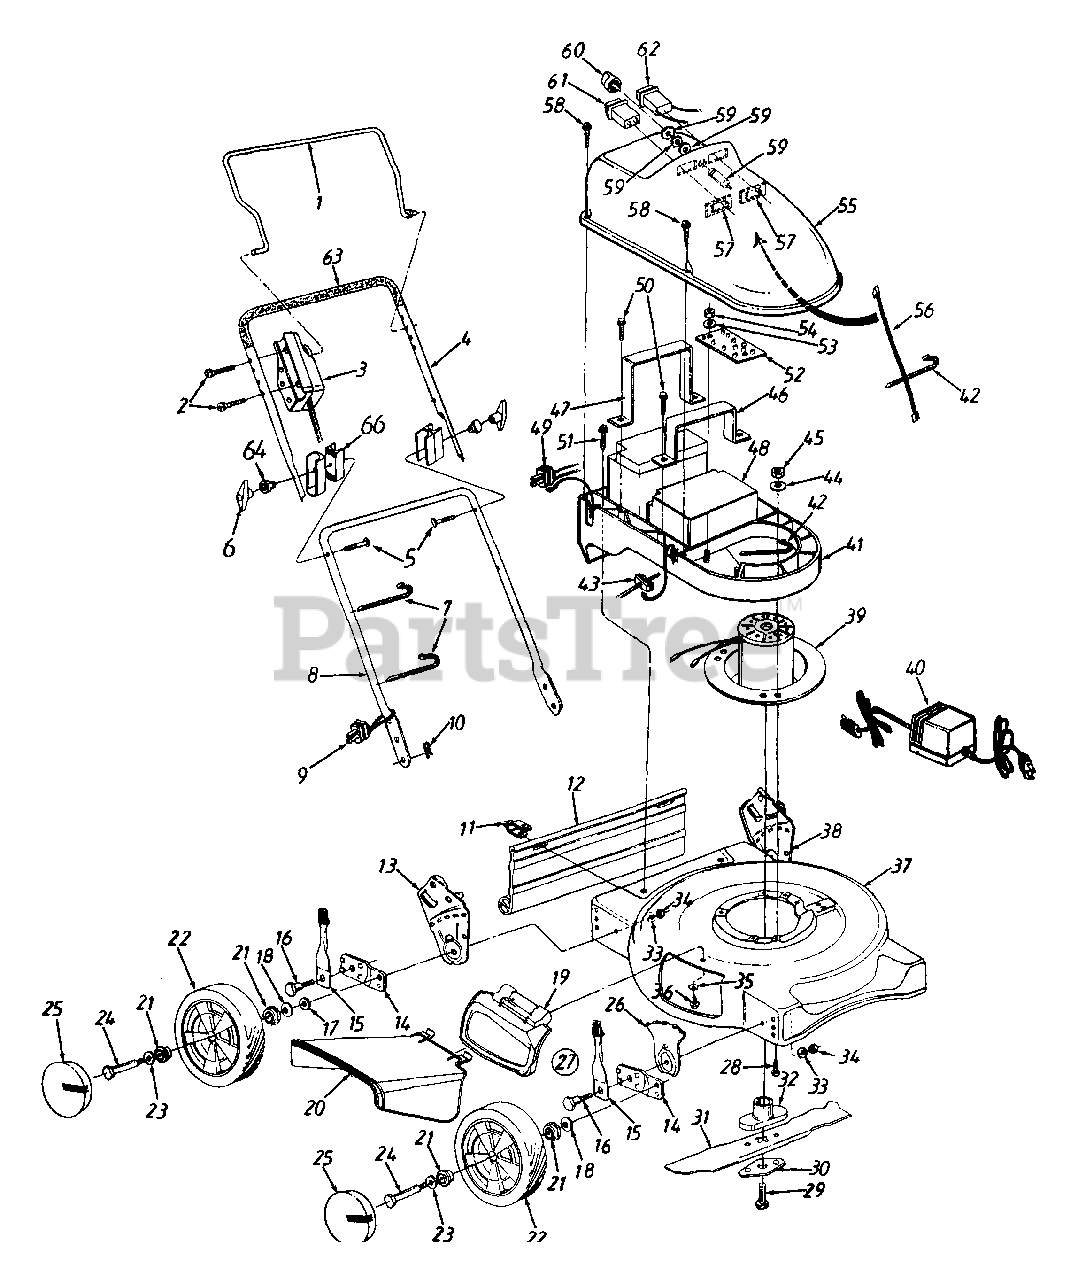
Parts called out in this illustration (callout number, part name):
1	Control Handle
2	C-Sunk Scr. 1/4-20 x 1.8" Lg.
3	Switch Ass'y.
6	Hand Knob
7	Cable Tie
8	Lower Handle
10	Hairpin Clip
11	Hinge Clip
12	Rear Flap
13	Handle Brkt. Ass'y. - R.H.
15	Spring Lever Ass'y. w/Knob
16	Shld. Bolt .5" Dia. x .43" Lg.
17	Fl-Wash. .385" I.D. x 1" O.D.
18	Bell-Wash. .38" I.D. x .88" O.D.
19	Mulching Plug Ass'y.
20	Chute Deflector
21	Ball Bearing
22	Wheel Ass'y.
23	Wave Wash. .51" I.D. x .75" O.D.
24	Shld. Bolt .498" Dia. x 1.45
25	Hub Cap
26	Height Adj. Plate
27	Height Adj. Ass'y. Comp. - R.F.
27	Height Adj. Ass'y. Comp. - L.F.
28	Hex Wash. Self-Tap Scr. 3/8-16 x 1" Lg.
29	Hex Bolt 3/8-24 x 2.5" Lg.
30	Blade Bell Support
31	18" Blade
32	Blade Adapter
33	Bell-Wash. .39" I.D. x 1.38" O.D.
34	Hex Nut 3/8-16 Thd.
35	Bell-Wash. 1/4" I.D.
36	Hex Wash. Hd. TT-Tap Scr. 1/4 x .5" Lg.
39	Motor Ass'y.
40	Charger
41	Tray Ass'y.
42	Cable Tie
43	Harness Ass'y. Switch
44	Fl-Wash. .406" I.D.
45	Hex L-Nut 3/8-16 Thd.
46	Front Bracket Ass'y.
47	Rear Bracket Ass'y.
48	Battery Ass'y.
49	Charger Plug
50	Hex Hd. Hi-Lo Scr. 1/4 x .75" Lg.
51	Hex Wash. Hd. TT-Tap Scr. 1/4-20 x 1" Lg.
52	Circuit Board
53	Fl-Wash. .21" I.D. x .56" O.D.
54	Palnut Self-Threading
55	Motor Cover
56	Key Switch Harness Ass'y.
57	Mounting Clamp
58	Hex AB-Tap Scr. #10 x .75" Lg.
59	Key Switch
61	Meter
62	Meter
63	Foam Grip
64	Insulator Knob
66	Lower Handle Insulator
